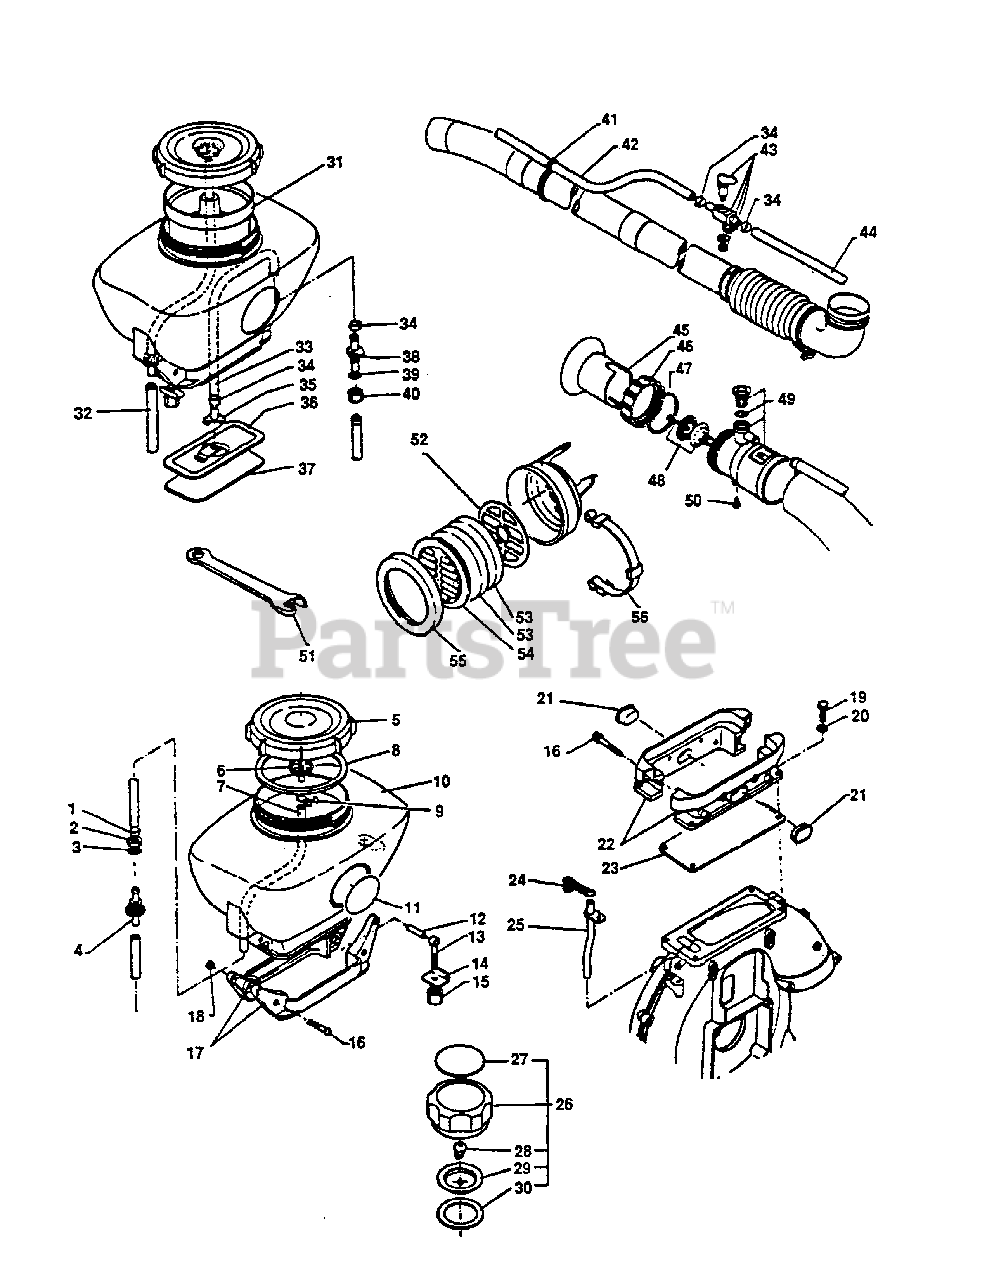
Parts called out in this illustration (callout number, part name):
1	CLAMP
3	WASHER 12×20×1
4	CONNECTOR, PIPE
5	CAP, CHEMICAL TANK
6	CONNECTOR, PIPE
7	PIPE, INNER PRESSURE 7×11×400BL
8	GASKET, CHEMICAL TANK
9	CLAMP
10	TANK, CHEMICAL
11	LABEL
16	SCREW 5×30
17	HOLDER
19	BOLT 6×20
22	CLAMP KIT
25	HOSE, AIR
26	CAP ASSY
27	LABEL - FUEL MIX
28	VALVE, CHECK
29	HOLDER, VENT
30	GASKET
33	HOSE, FLUID
34	CLIP - 14
35	MOUTH, SUCTION
38	CONNECTOR, PIPE
39	O-RING 3×13
41	CLIP
42	HOSE
43	VALVE ASSY
44	HOSE, FLUID
45	COLLAR, NOZZLE
47	RING, NOZZLE
48	NOZZLE ASSY
49	ADJUSTER, VOLUME
50	SCREW 5×12
51	SPANNER 10×21
52	RETAINER, AIR FILTER
53	FILTER, AIR
54	COVER, AIR FILTER
55	COVER, AIR FILTER
56	CLAMP
